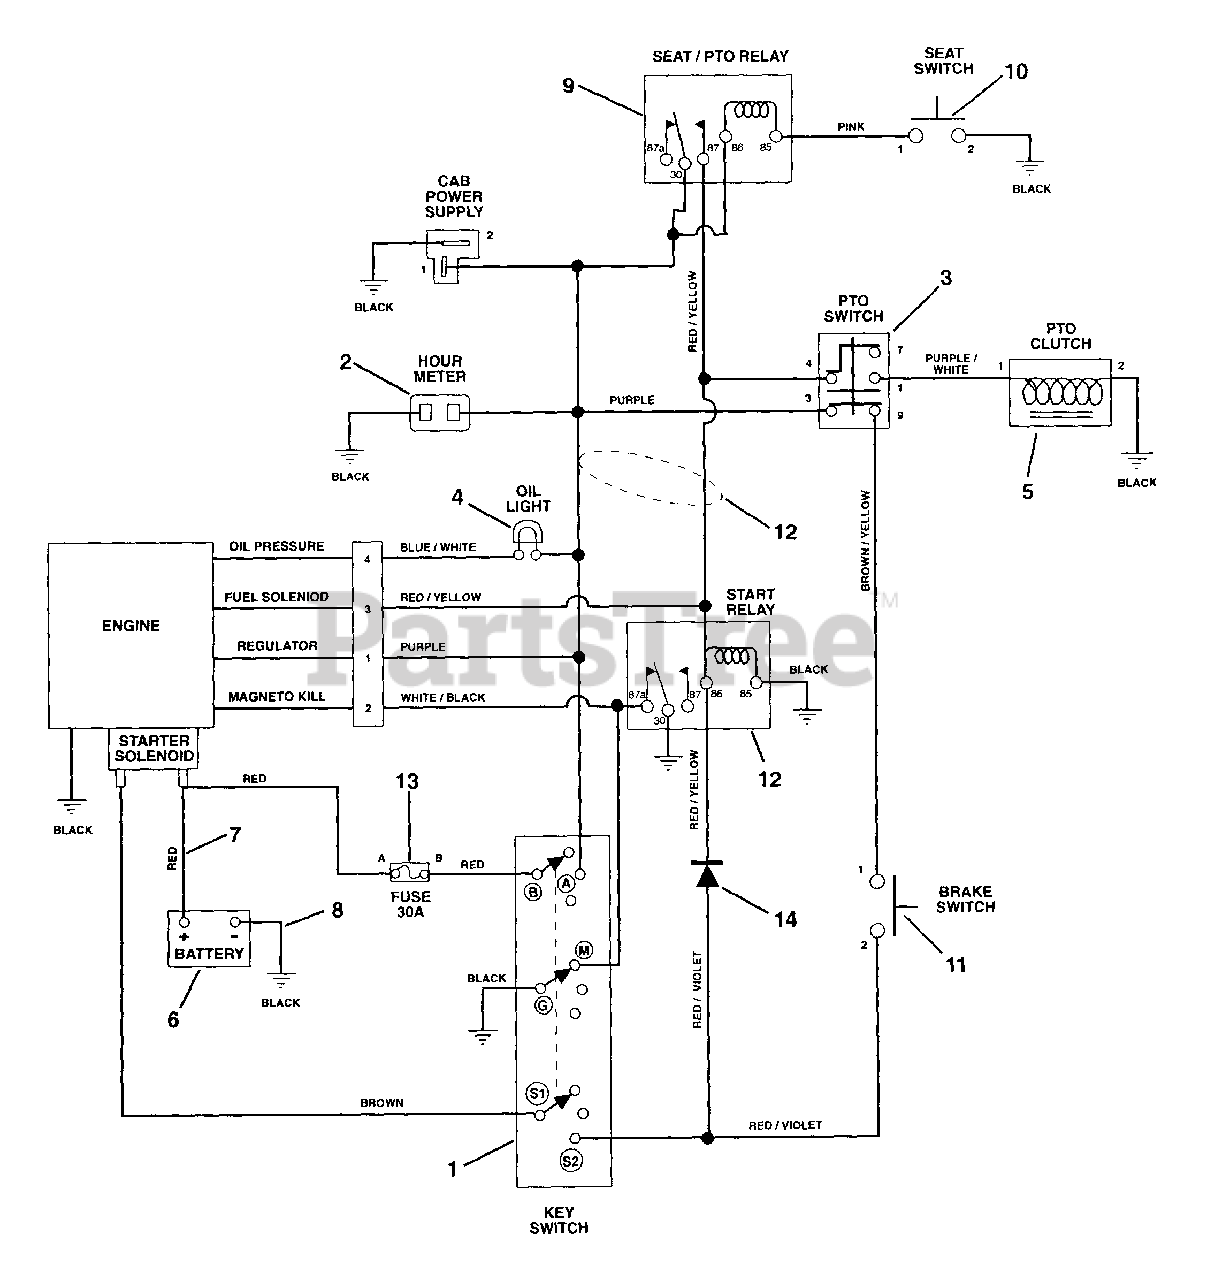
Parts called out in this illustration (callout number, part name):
1	Key Switch
2	Hour Meter
3	Switch-Clutch With Retainer Ring
4	Light-Indicator
5	Electric Clutch
6	Battery with Tube
7	Cable-Battery To Solenoid
8	Ground Cable
9	Relay
10	Seat Switch
11	Switch-Single Pole
12	Harness Kohler
14	Molded Diode Plug-Black 1-Amp
